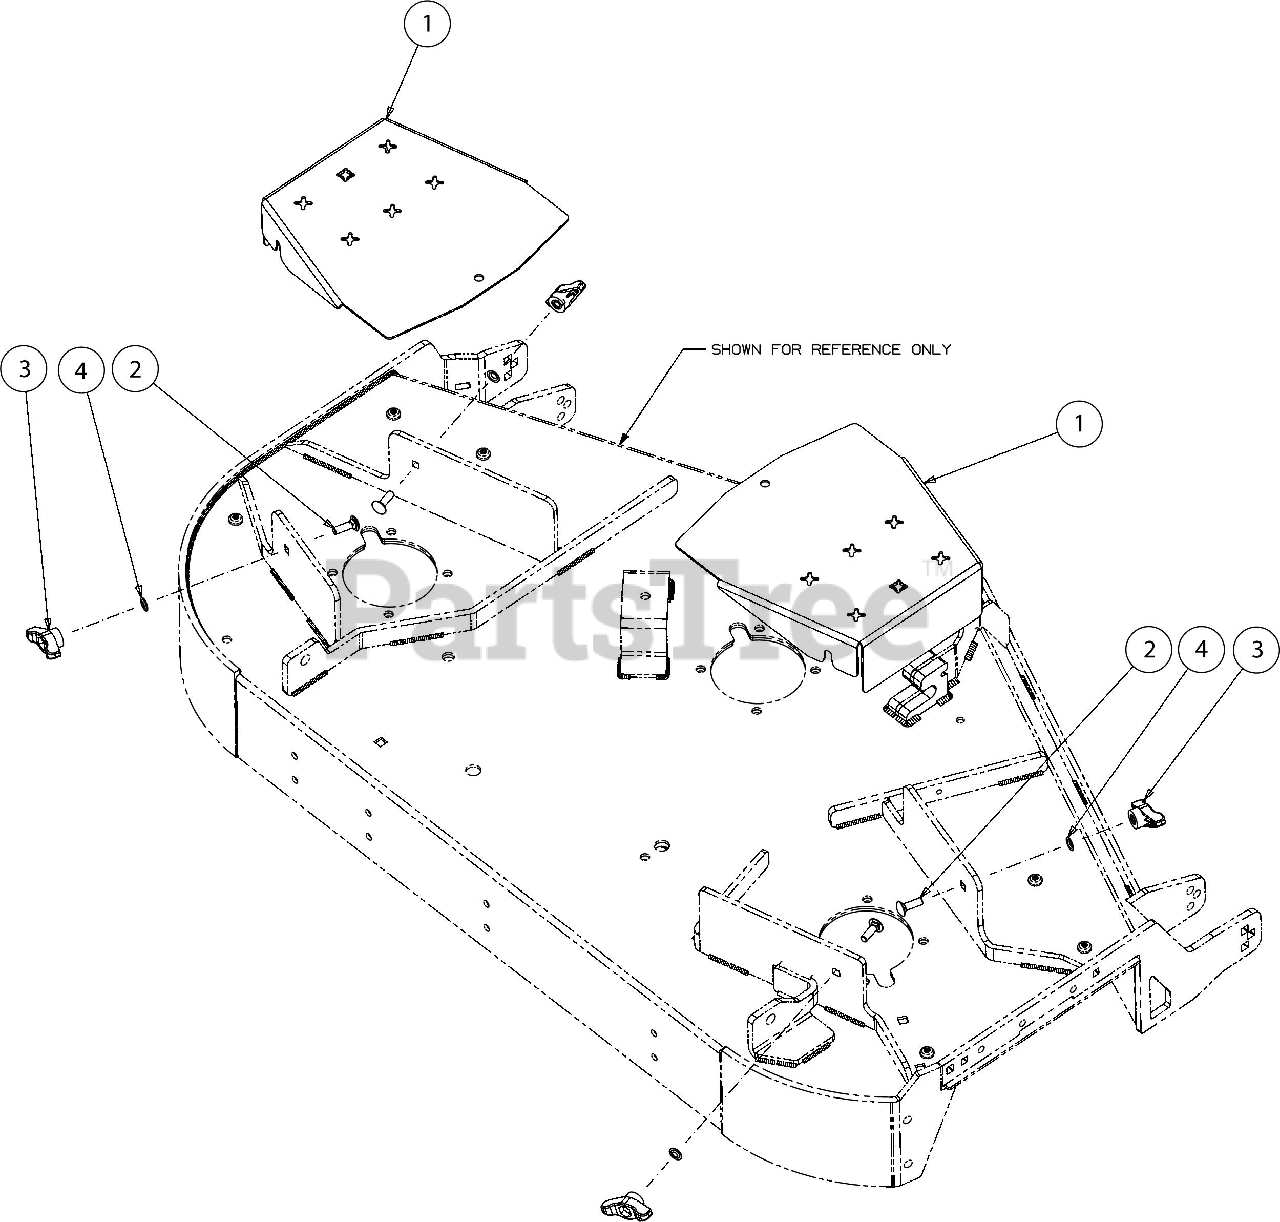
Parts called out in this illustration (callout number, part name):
1	BELT COVER
2	CARRIAGE BOLT 5/16-18 x 1.00
3	WING KNOB 5/16-18
